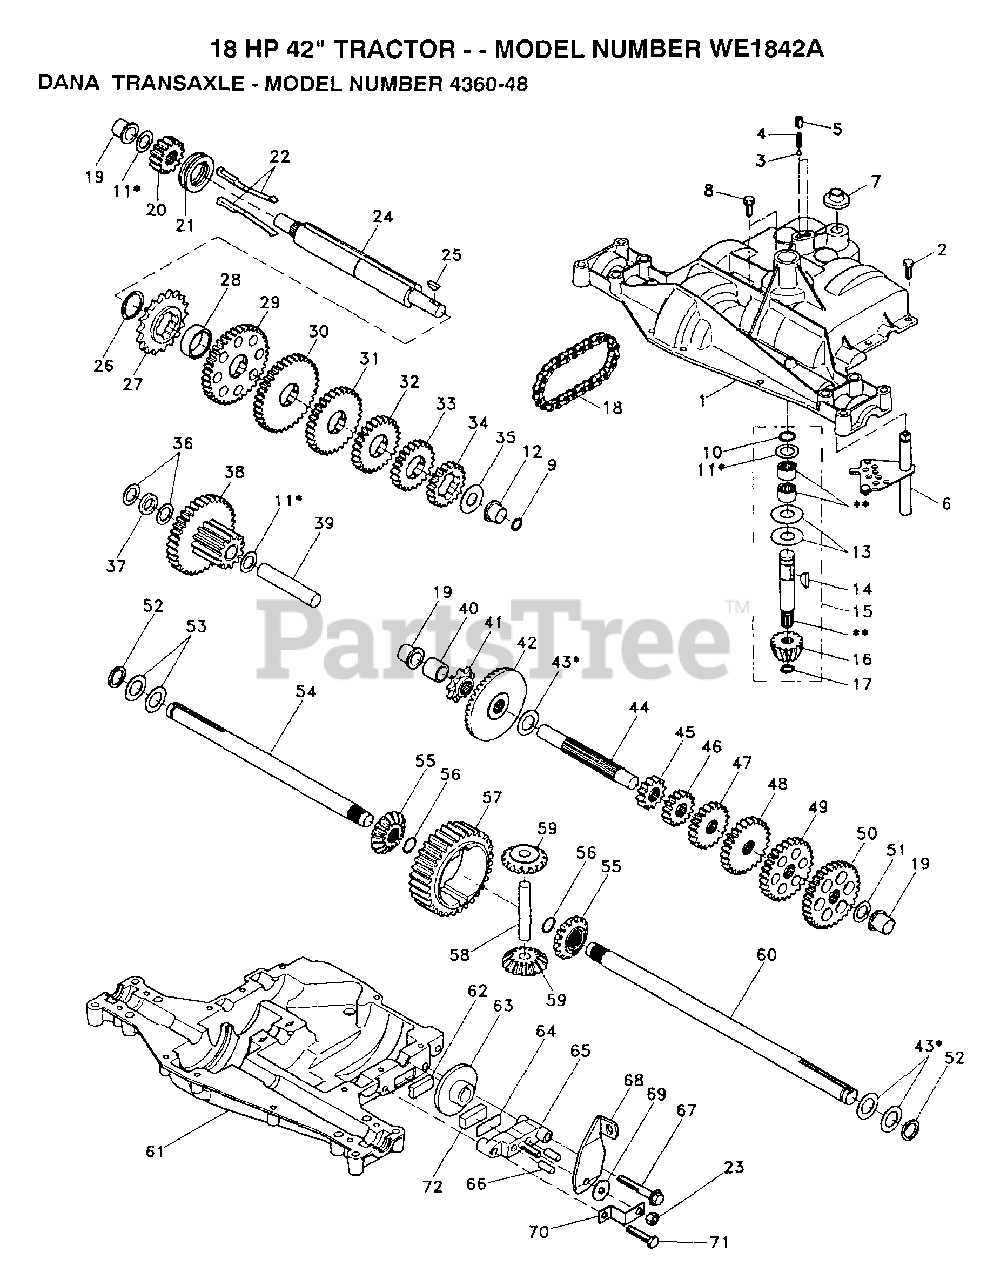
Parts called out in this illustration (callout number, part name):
1	HOUSING UPPER
3	BALL, DETENT
4	SPRING, DETENT
5	SCREW, SET
6	SHIFTER ASSEMBLY
7	BOOT, SHIFTER
8	SCREW TAPPING WITH SEALER
9	SQUARE RING
10	RING RETAINING
11	ASSY, KIT, SHIM .625 SHAFT
12	BEARING FL
13	WASHER, PLAIN .632 X 1.38 X .046
14	KEY WOODRUFF #9
15	ASSEMBLY, KIT, INPUT SHAFT
16	PINION, BEVEL, 14 TEETH
17	RING, RETAINING
18	CHAIN, 24 PITCHES
19	BEARING, FLANGE
21	COLLAR, CLUTCH
22	ASSEMBLY, KIT, CLUTCH KEYS
23	LOCKNUT 5/16-24
24	SHAFT INTERMEDIATE
25	KEY, WOODRUFF, #61
26	RING, RETAINING
27	SPROCKET, 18 TEETH
29	GEAR, SPUR, 37 TEETH
30	GEAR, SPUR, 35 TEETH
31	GEAR, SPUR, 30 TEETH
32	GEAR, SPUR, 25 TEETH
33	GEAR, SPUR, 22 TEETH
34	GEAR, SPUR, 19 TEETH
35	WASHER, PLAIN .640 X 1.37 X .061
36	WASHER, PLAIN .632 X 1.00 X .026
37	SPACER .630 X 1.00 X .169
38	ASSY GEAR COMB 12&35 TEETH
39	SHAFT, IDLER
40	SPACER .635 X .875 X .755
41	SPROCKET, 9 TEETH
42	GEAR, BEVEL, 42 TEETH
43	ASSY, KIT, SHIM .750 SHAFT
44	SHAFT, DRIVE
45	GEAR, SPUR, 12 TEETH
46	GEAR SPUR, 15 TEETH
47	GEAR, SPUR, 20 TEETH
48	GEAR, SPUR, 25 TEETH
49	GEAR, SPUR, 25 TEETH
50	GEAR, SPUR, 31 TEETH
51	WASHER, PLAIN .632 X 1.00 X .060
52	WASHER, NEOPRENE
53	WASHER, PLAIN .758 X 1.25 X .031
54	AXLE LEFT HAND
55	GEAR, MITER, 15 TEETH
56	RING, RETAINING
57	GEAR, SPUR, 32 TEETH
58	SHAFT, CROSS
59	GEAR, MITER, 15 TEETH
60	AXLE, R.H.
61	HOUSING LOWER
62	PUCK, FRICTION
63	DISC, BRAKE
65	JAW, BRAKE
66	PIN, DOWEL
67	SCREW, SELF-TAPPING
68	LEVER ACTUATING
69	WASHER, PLAIN .321 X 1.00 X .055
70	BRACKET, ANTI-ROTATION
71	SCREW TAPPING
72	PUCK, FRICTION
